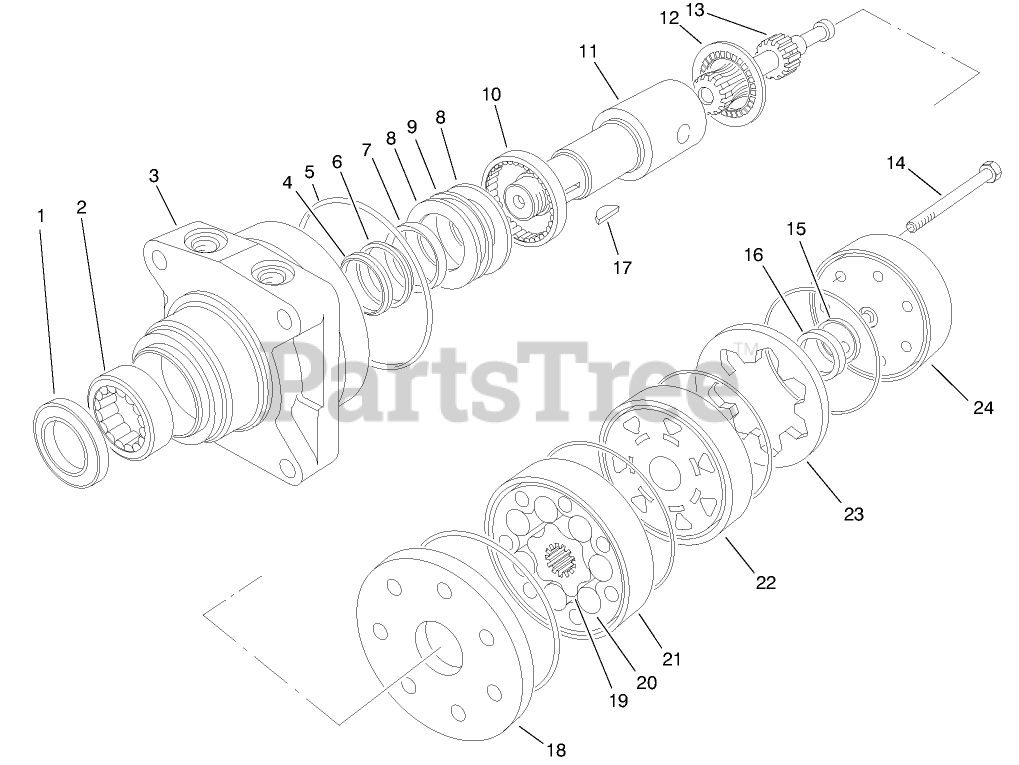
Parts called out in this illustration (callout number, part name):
4	Washer
11	SHAFT-COUPLING
13	Link-Drive
14	SCREW-CAP, HH
17	KEY-WOODRUFF
18	Plate-Wear
22	Manifold
24	End Cover Assembly
